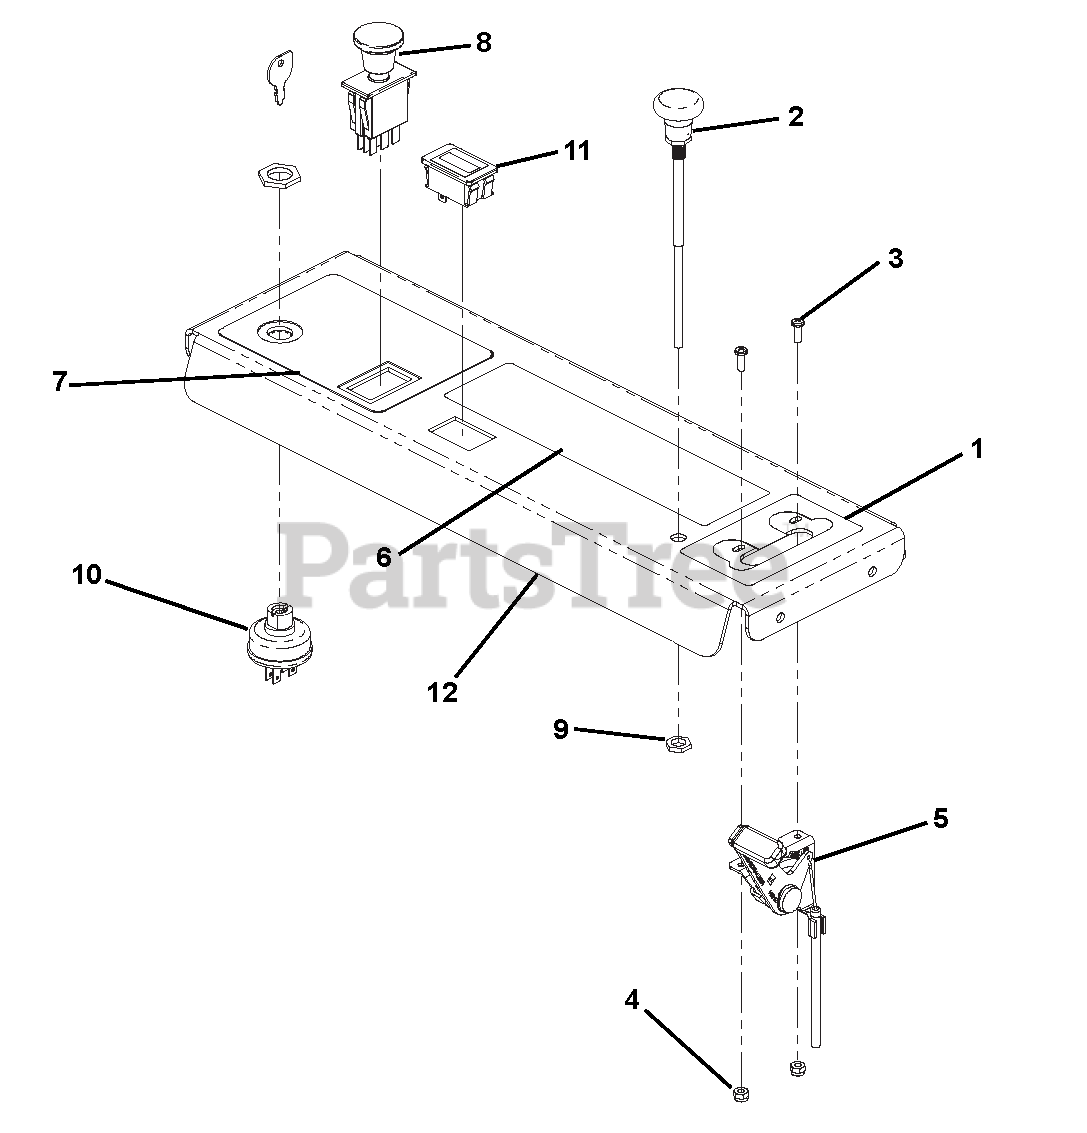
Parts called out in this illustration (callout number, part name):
1	DECAL, THROTTLE
2	CABLE, CHOKE
3	@BLT-HEX 8-32 X .5 YWZC
4	@NUT-LK-NYL 8-32 W/INSTR YWZC
5	CABLE, THROTTLE
6	DECAL, GENERAL CAUTION
7	DECAL, PTO/IGNITION
8	SWITCH, PTO ENGAGEMENT
9	@NUT-HEX .38-16 YWZC
10	SWITCH, KEY - 3 POSITION
11	HOUR METER - DIGITAL
12	ASSEMBLY, ARIENS CONTROL PANEL
